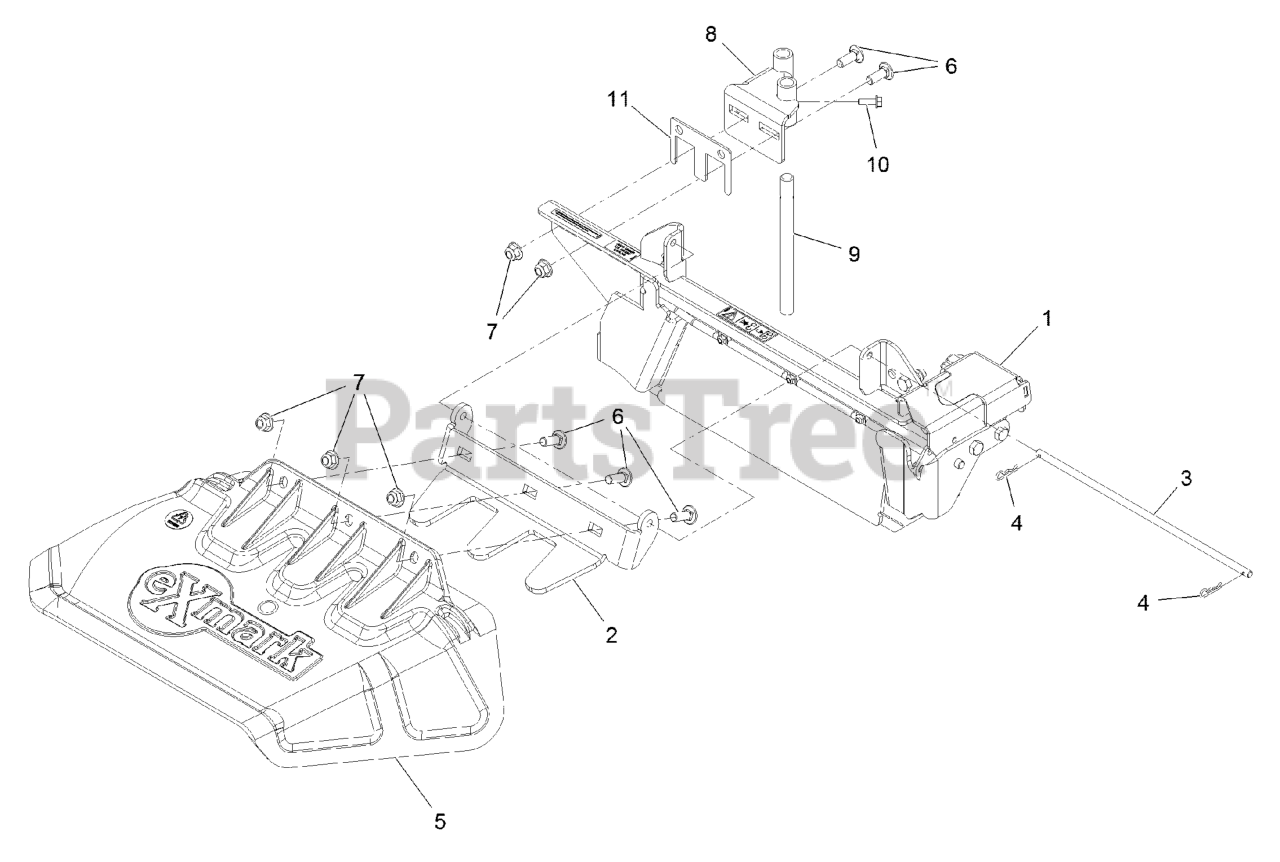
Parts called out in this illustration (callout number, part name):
1	ASM, OCD GATE
2	MOUNT, DISCHARGE CHUTE
3	PIN,CHUTE
4	PIN-COTTER
5	CHUTE,DISCHARGE
6	SCREW-CARR
7	NUT-HF, NI
8	WELDMENT, OCD MOUNT
9	PIN-MOUNT, OCD
10	SCREW-HHF
11	SHIM-OCDWB
